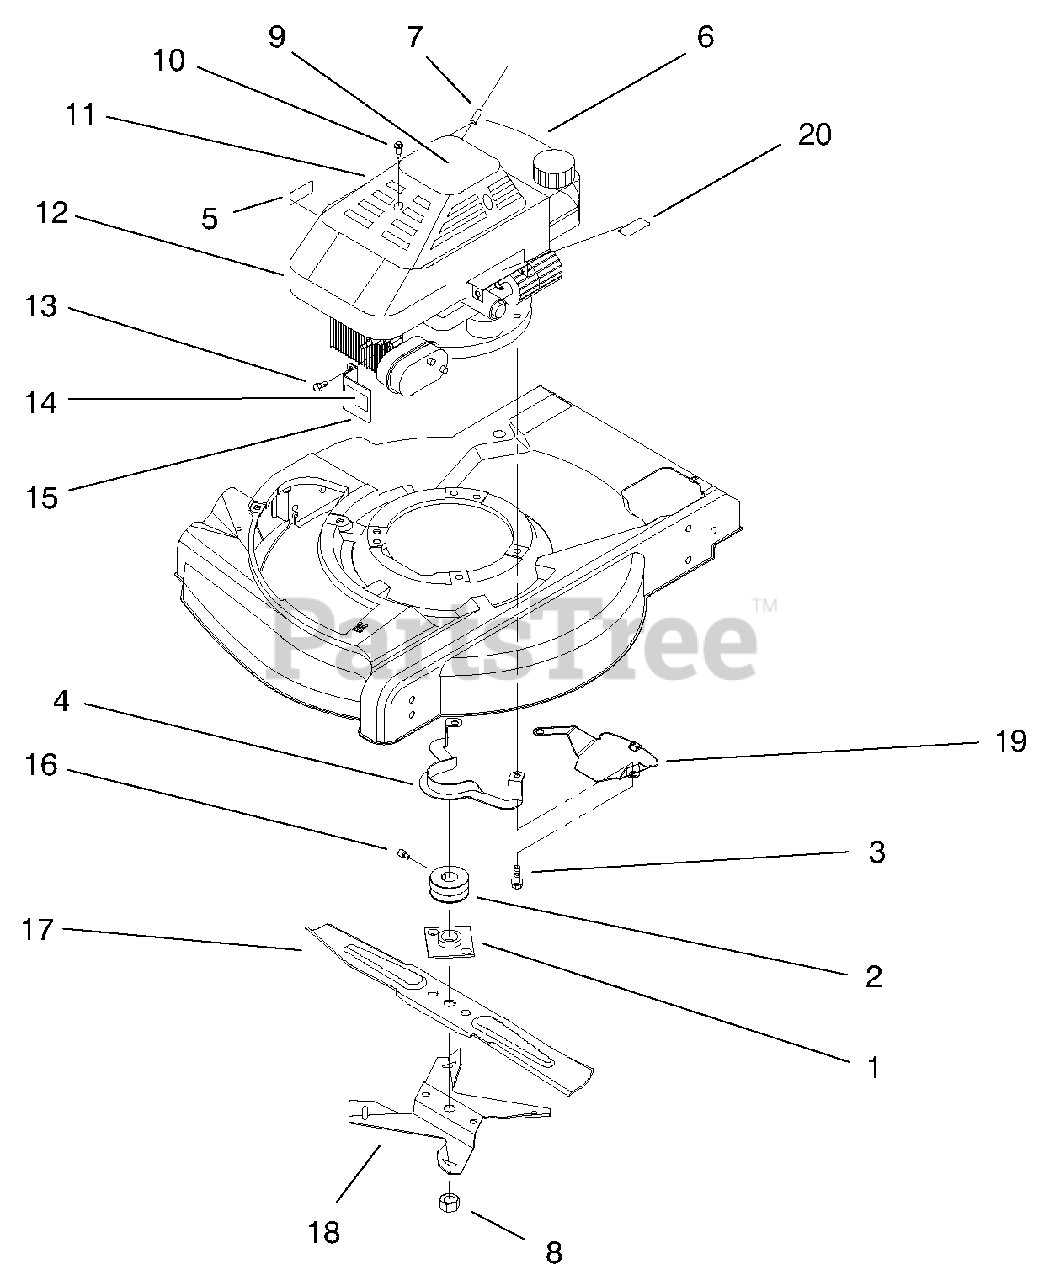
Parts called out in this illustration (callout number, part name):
1	ASM-Plate & Collar
2	Pulley-Engine
3	Screw-Engine Mount
4	Guide-Belt
5	Decal-Oil Instruction
6	ASM-Engine
7	Rope-Stop
8	Nut-Blade
9	Decal-Recoil
10	Screw-Recoil Cover
11	Cover-Starter
12	Shroud-Engine
13	Screw-HSH
14	Decal-Warning
15	Guard-Muffler
16	Screw-Set
17	Blade-21" Whirl
18	Fan-Mulching
19	Shield-Grass
20	Decal-Primer
